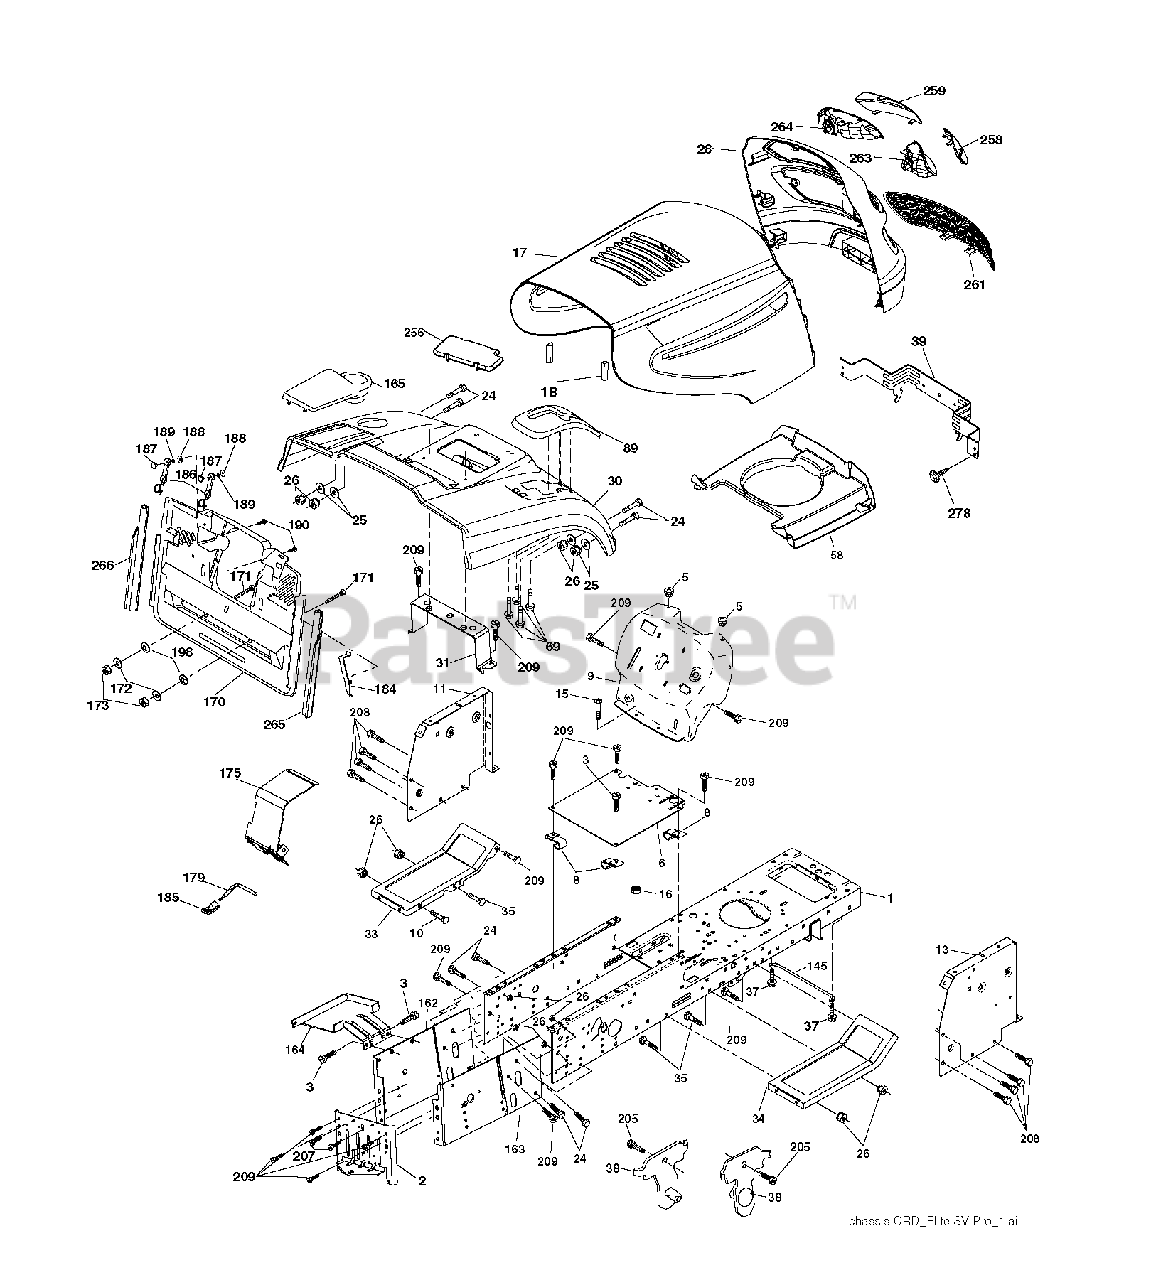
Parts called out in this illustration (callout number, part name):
1	CHASSIS
3	SCREW 3/8-16X3/4
5	BUMPER.RUBBER.HOOD
8	CLIP,INSULATOR
10	BOLT D
11	PANEL.DASH.LH.LTX
13	PANEL DASH RH
16	NUT
18	BUMPER.HOOD.LARGE.1.75"
25	WASHER
26	NUT
31	BRACKET SUPPORT FENDER
39	BRACKET PIVOT
69	SCREW.HI-LO.CONSOLE
145	ROD.PIVOT.HOOD
164	SUPPORT
171	BOLT
172	WASHER
186	LATCH ASSY
187	WELDNUT
189	LOCKWASHER
207	SCREW, 5/16-18 X 1/2
208	SCREW 3/8-16X1/2
209	SCREW, 3/8-16X3/4
263	BEZEL GRILL RH
264	BEZEL GRILL LH
278	SCREW
